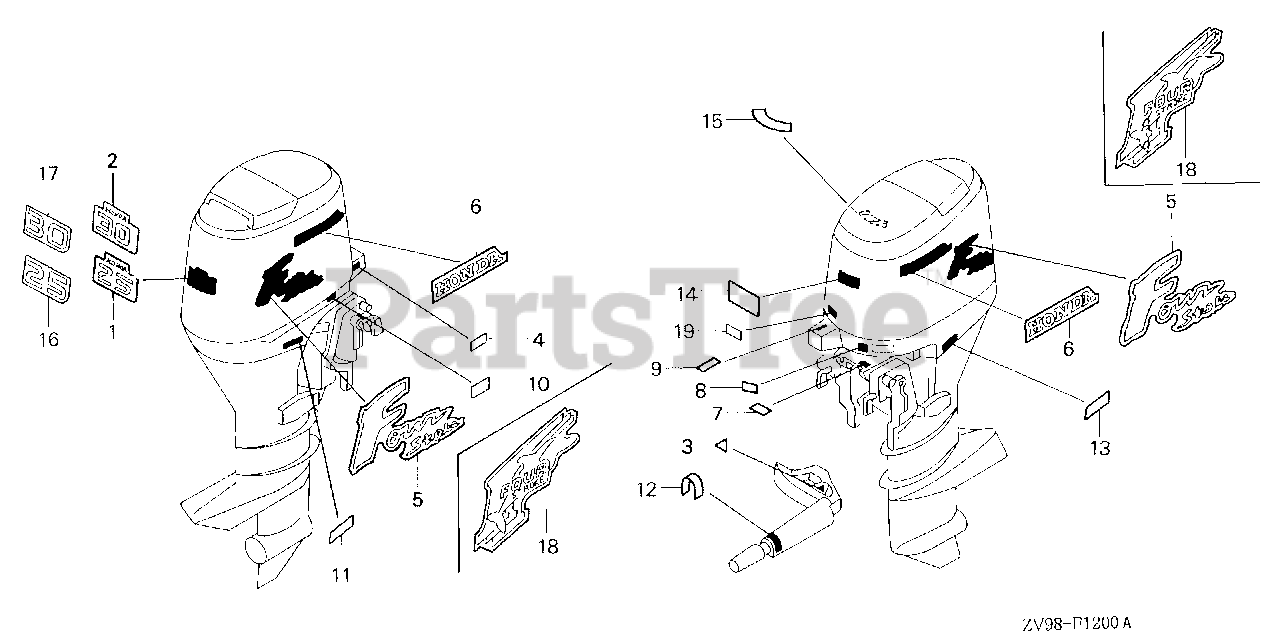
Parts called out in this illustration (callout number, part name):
1	EMBLEM, RR. (25)
3	MARK, EMERGENCY SWITCH INDICATION (ENGLISH)
5	MARK, SIDE EMBLEM
6	MARK, SIDE STRIPE
7	LABEL, SPECIFICATION
8	MARK, OIL PRESSURE
9	MARK, CHANGE (ENGLISH)
10	MARK, RECEPTACLE (6A)
11	LABEL, OIL CAUTION (ENGLISH)
12	MARK, THROTTLE (ENGLISH)
13	LABEL, STORING CAUTION (ENGLISH)
14	LABEL, CAUTION OPERATOR (ENGLISH)
15	MARK, EMERGENCY START (ENGLISH)
